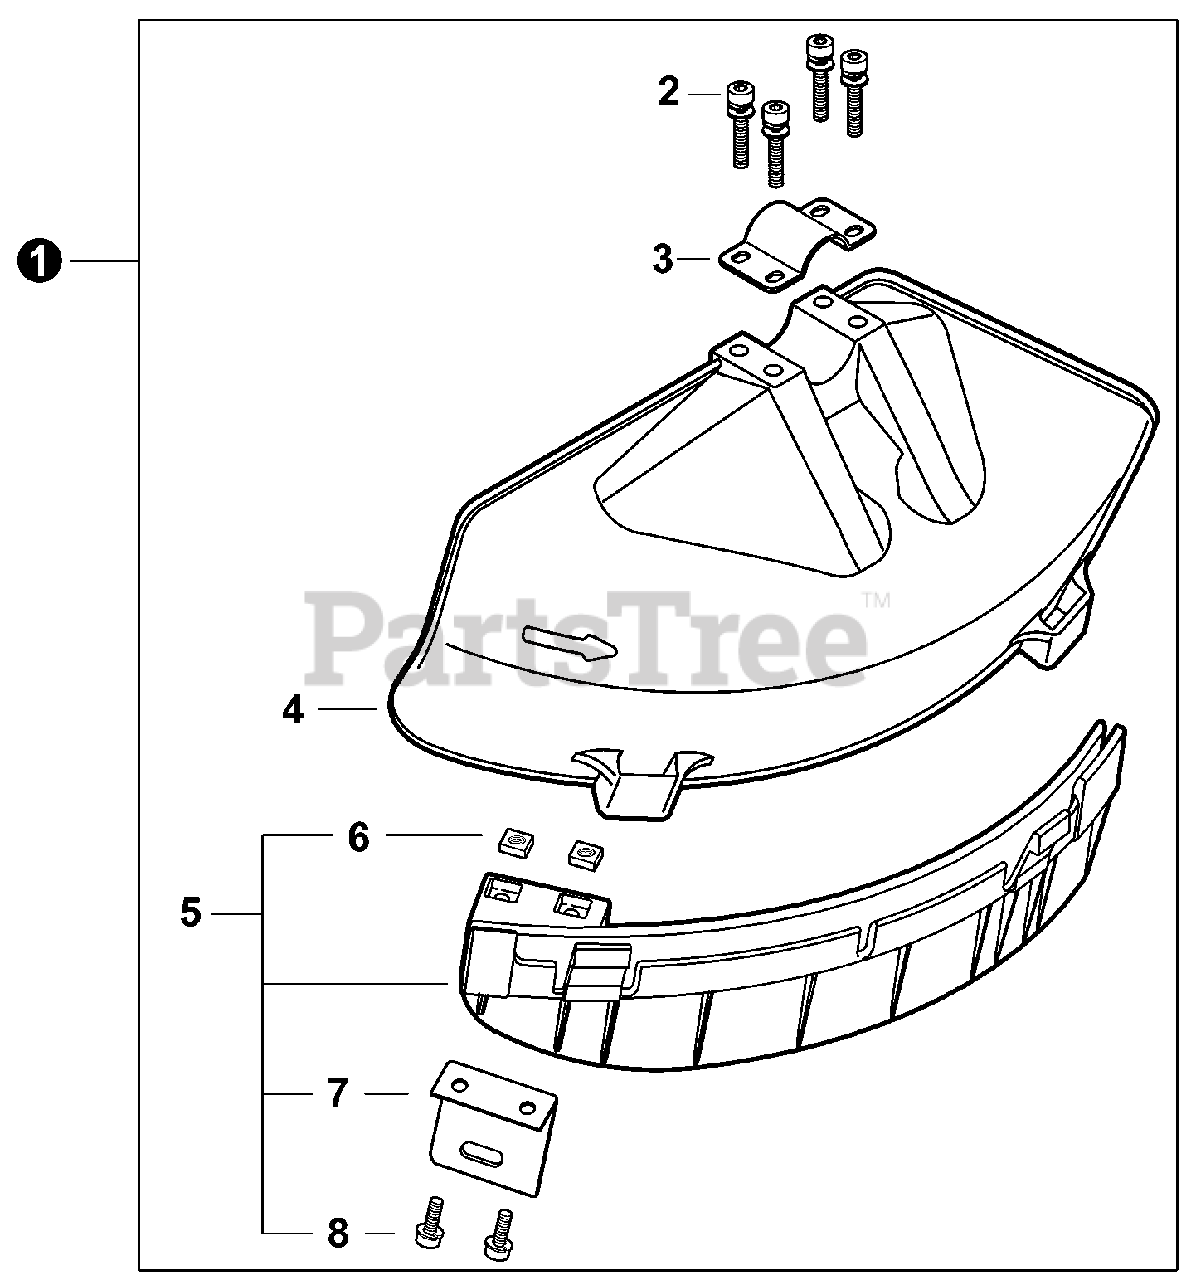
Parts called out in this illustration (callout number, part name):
1	DEBRIS SHIELD KIT
2	BOLT M5x45
3	CLAMP, UPPER
4	SHIELD, DEBRIS PLASTIC
5	DEBRIS SHIELD EXTENSION ASSY
6	NUT M5
7	CUTTER
8	BOLT 5x16
